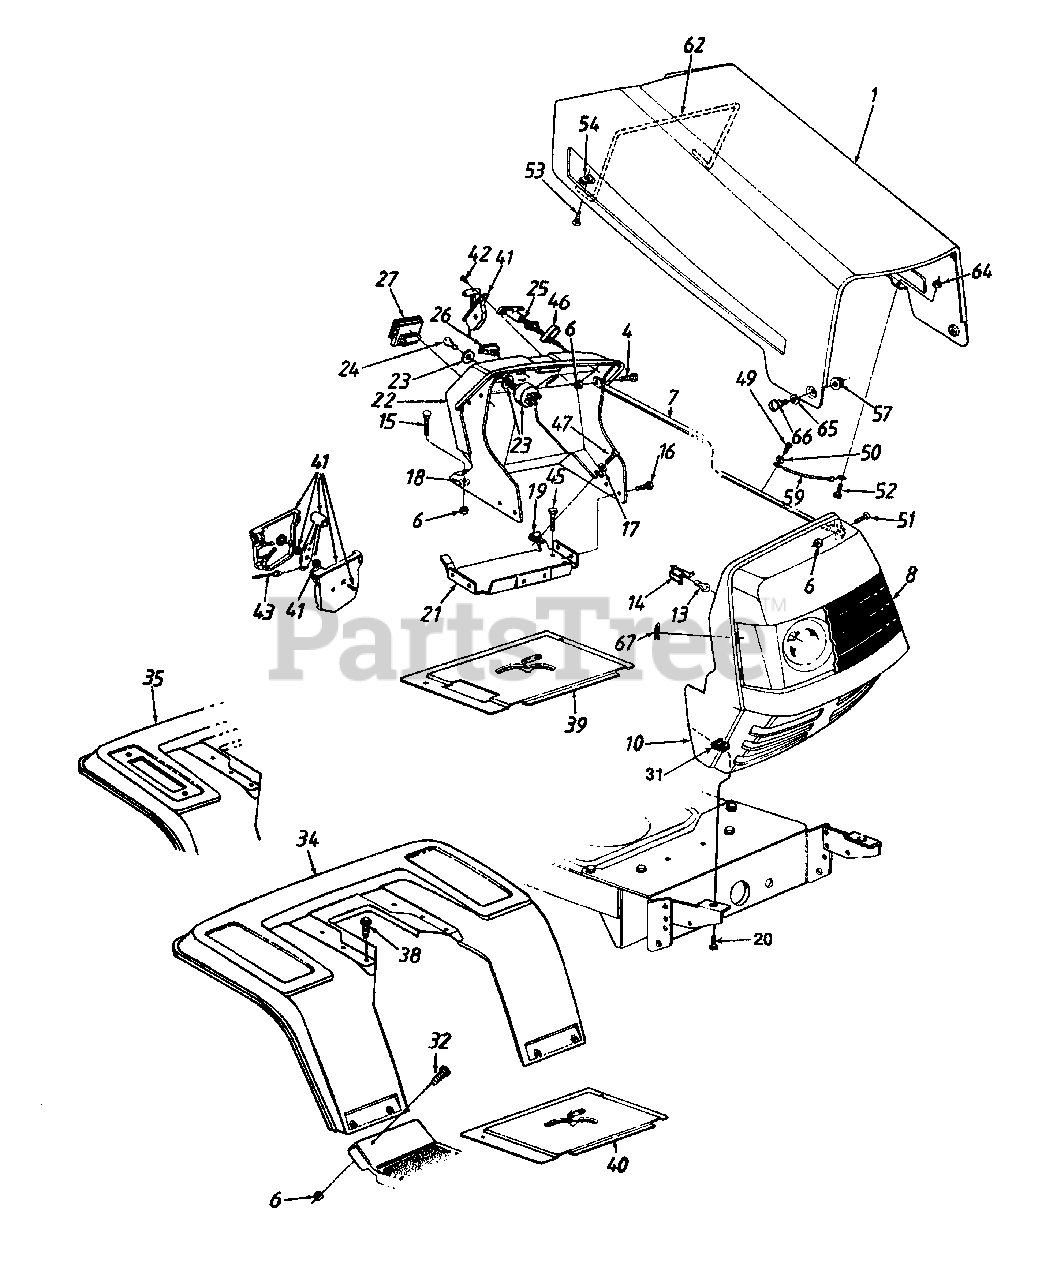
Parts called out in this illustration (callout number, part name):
6	Hex Sems Nut 1/4-20 Thd.
14	Socket
15	Carriage Bolt 1/4-20 x .75" Lg.
16	Hex Wash. Hd. TT-Tap Scr. 1/4-20 x .5" Lg.
17	Fl-Wash. .281" I.D. x .73" O.D.
18	Bolt Retainer 1/4" I.D.
19	Speed Nut 1/4-20 Thd.
20	Hex Bolt 5/16-18 x .75" Lg.
23	Ignition Switch
24	Ignition Key
25	Choke Control 23" Lg.
26	Light Switch
27	Ammeter
31	U-Nut 5/16-18 Thd.
32	Truss Mach. Scr. 1/4-20 x .5" Lg.
41	Throttle Box Ass'y.
42	Truss Mach. AB-Tap Scr.#10 x .5" Lg.
43	Throttle Control Wire 18.5" Lg.
45	Hex Wash. Hd. B-Tap Scr.5/16-18 x .5" Lg.
46	Choke Retainer
47	Hex TT-Tap Scr. 1/4-20 x .75" Lg.
49	Truss Mach. B-Tap Scr.#10 x .5" Lg.
50	Fl-Wash. .218" I.D. x .62"
51	Pan Hd. Mach. Scr. 1/4-20 x .75"
52	Truss Mach. Scr. #10-24 x .5" Lg.
53	Truss Mach. Scr. #10-24 x .75"
54	Speed Nut
57	Flange L-Nut 1/4-20 Thd.
59	Hood Stop
62	Hood Spring
64	Hex Sems Nut #10-24 Thd.
65	Spr. Wash. .39" I.D. x .62" O.D.
66	Shld. Bolt
67	Hairpin Clip 5/16" Dia.
